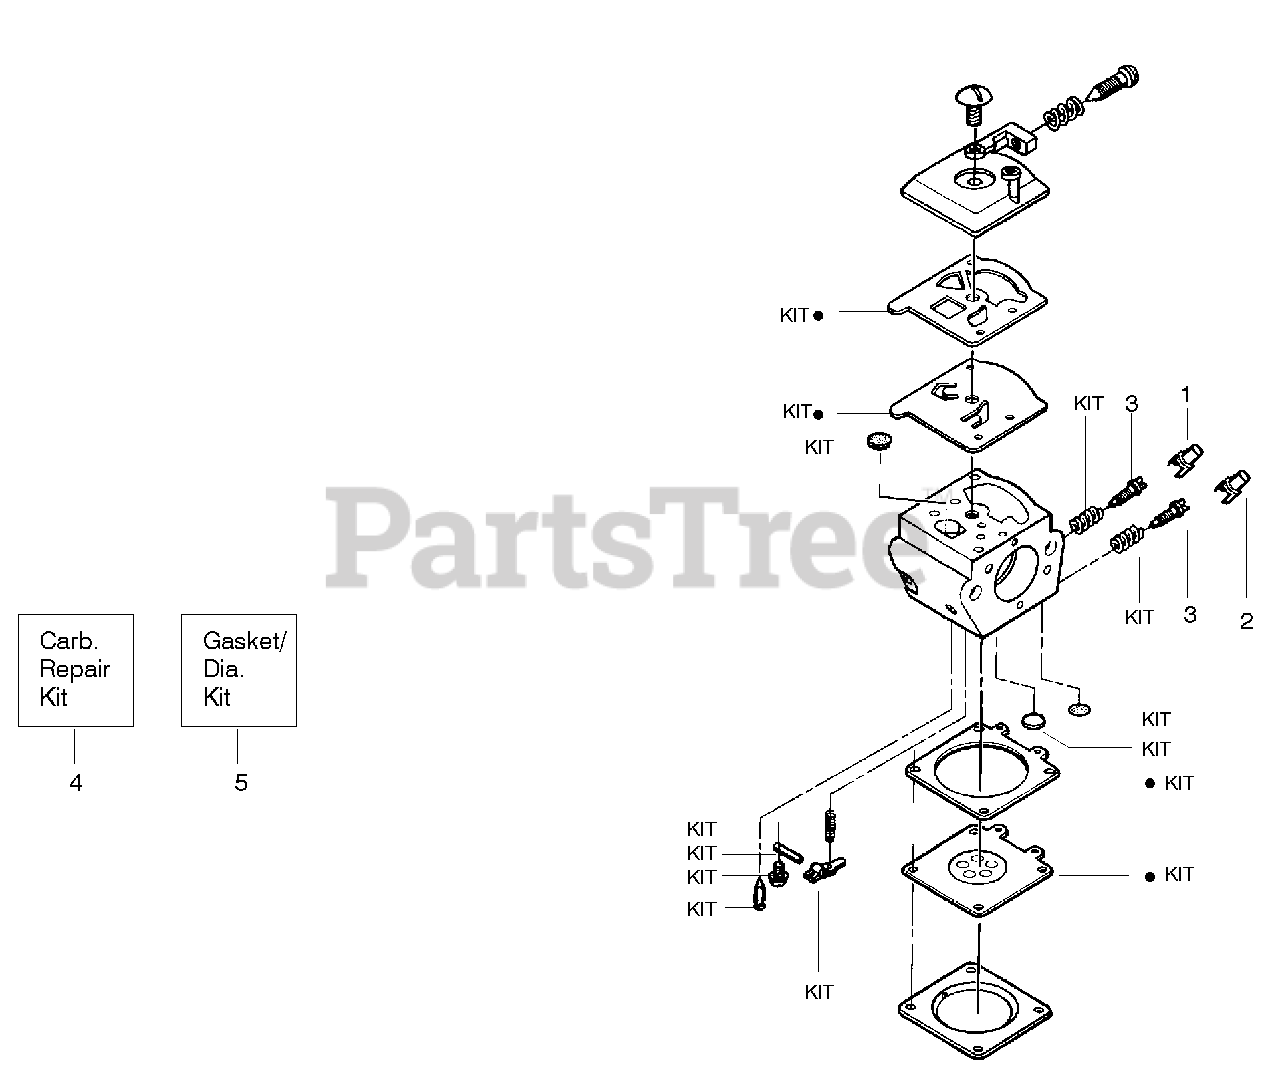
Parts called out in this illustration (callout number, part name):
1	Limiter Cap-High (Brown)
2	Limiter Cap-Low ( Tan)
3	Needle-High/Low Speed
4	Carburetor Repair Kit (KIT= Indicates Contents)
5	Gasket Diaphragm Kit (Indicates Contents)
